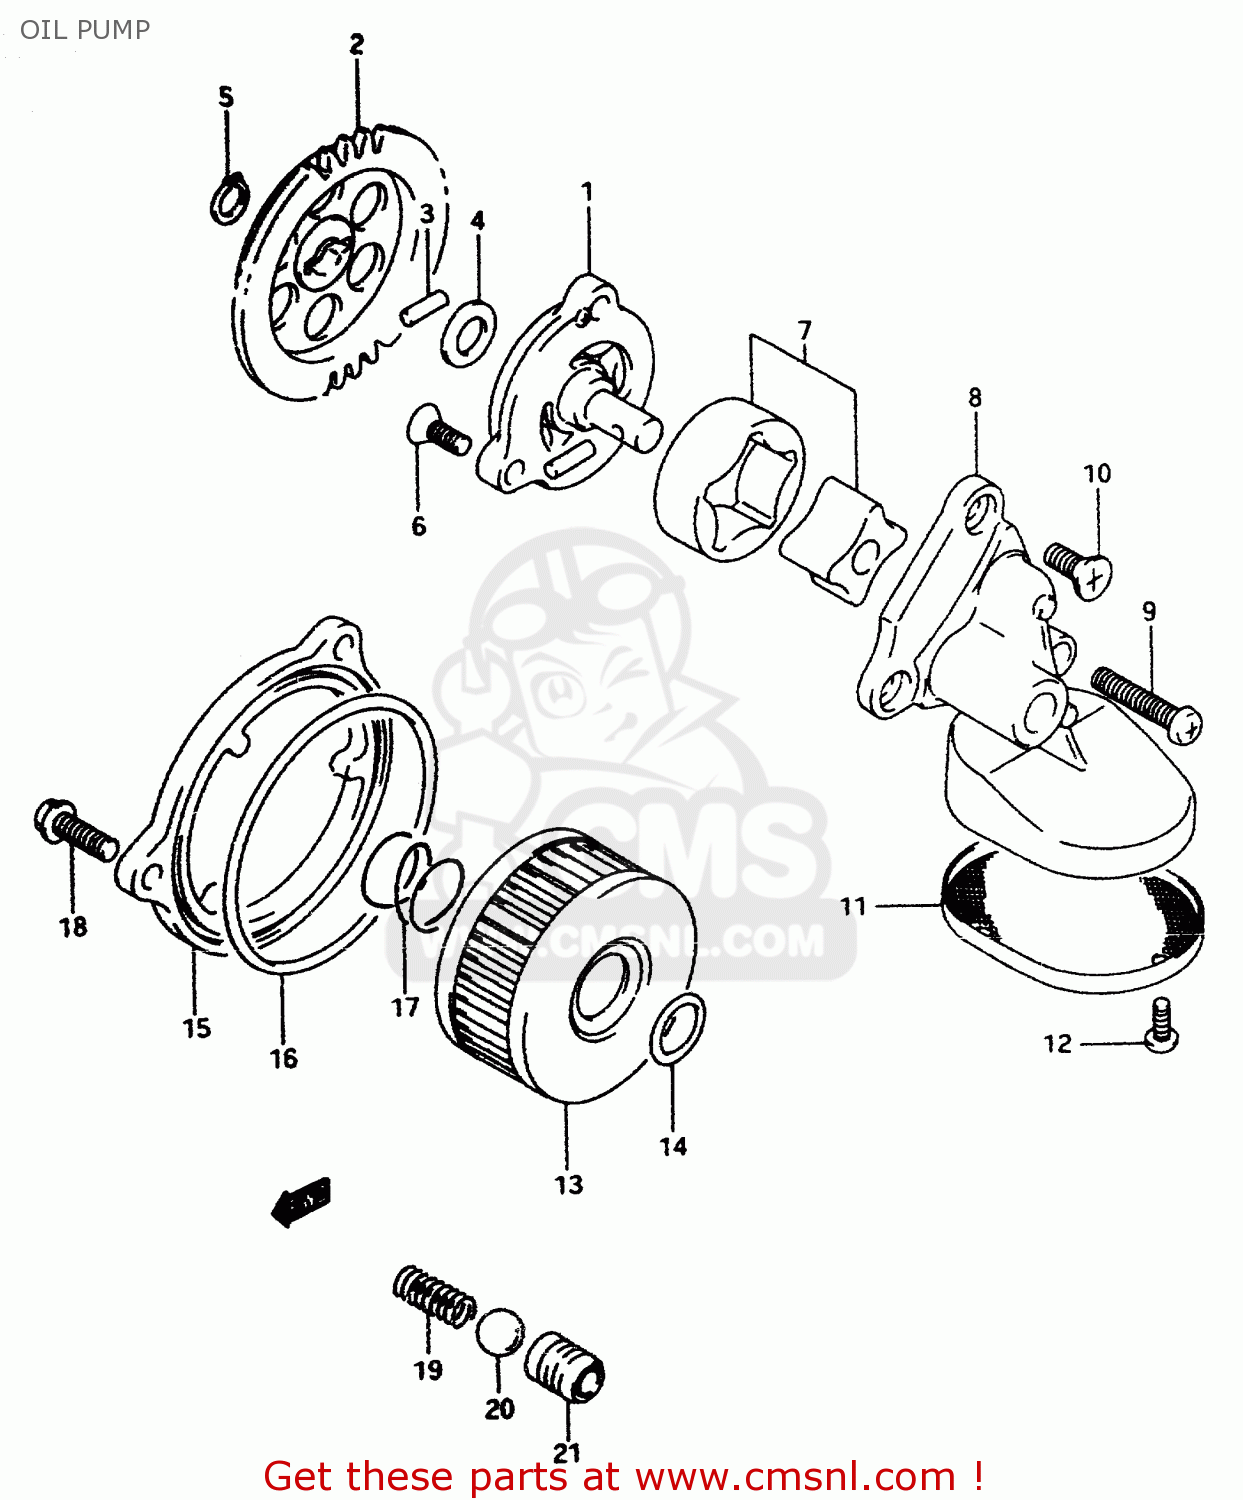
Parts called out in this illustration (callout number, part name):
1	PUMP ASSY,ENGINE OIL NO.1
2	GEAR,OIL PUMP DRIVEN (N
3	PIN(4X15.8)
4	SHIM(10X18X0.5)
5	CIRCLIP,10MM
6	SCREW ,6X16
7	ROTOR SET,OIL PUMP,NO.2
8	COVER,OIL PUMP NO.2
9	SCREW 6X30
10	SCREW ,6X16
11	STRAINER,OIL PUMP NO.2
12	SCREW
13	FILTER ASSY,ENGINE OIL
14	O RING(D:2.4,ID:15.8)
15	CAP,OIL FILTER
16	O RING(D:2.4,ID:73)
17	SPRING
18	SCREW
19	SPRING
20	BALL
21	SEAT,OIL CHECK VALVE
